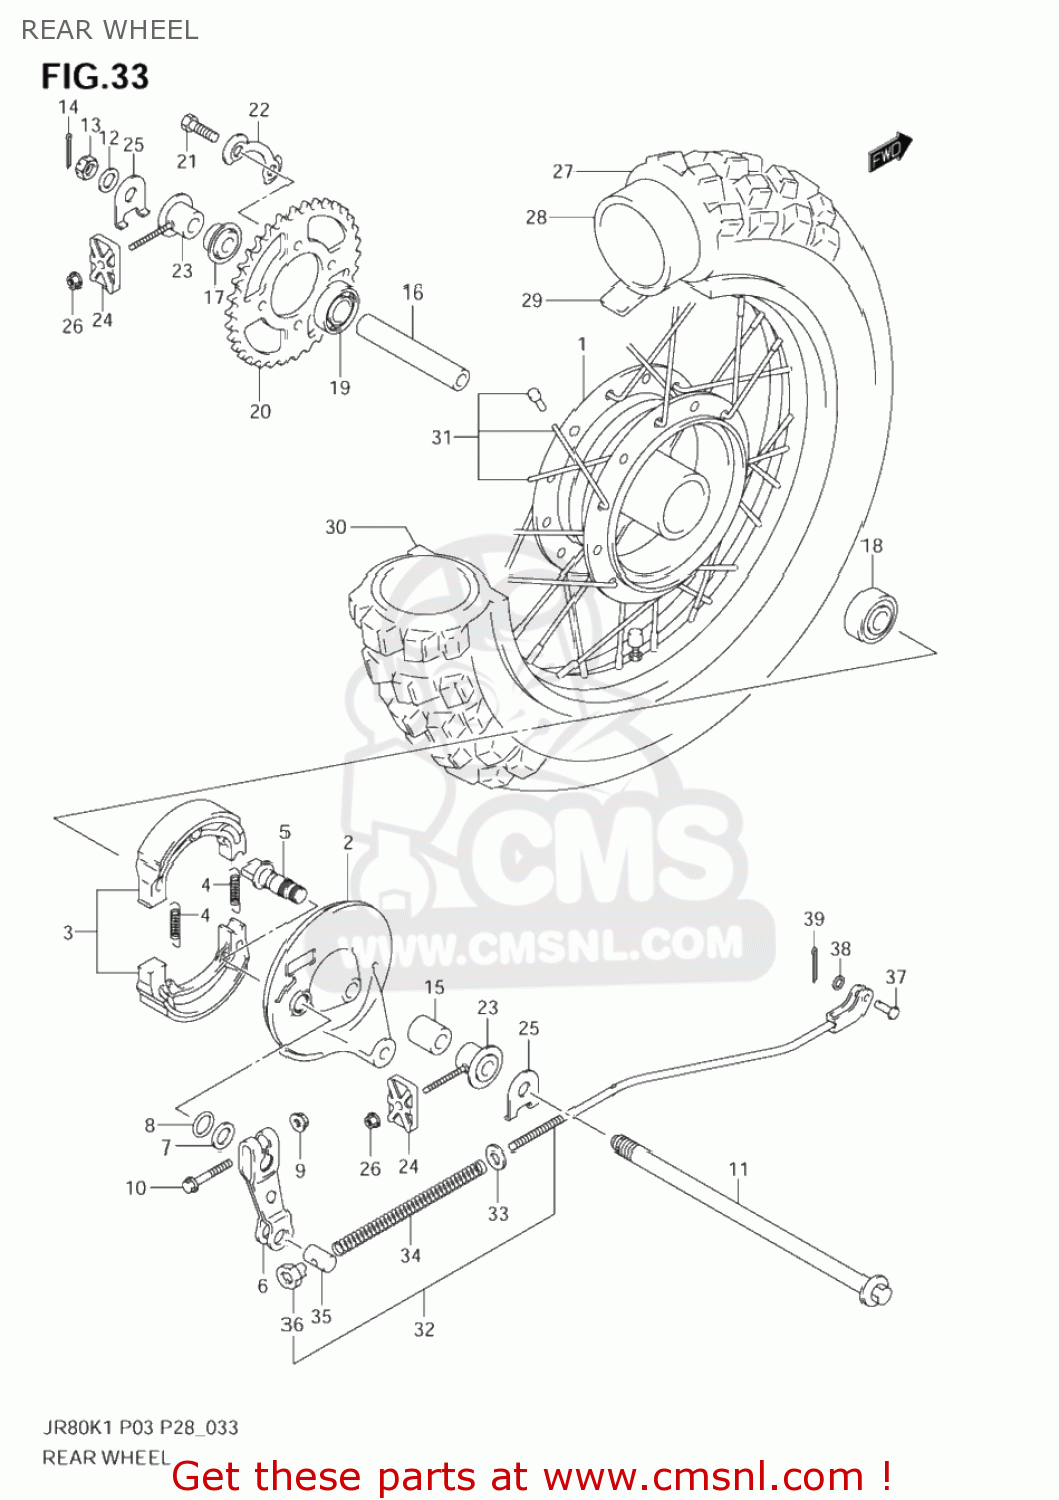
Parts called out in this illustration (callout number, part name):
1	HUB,RR
2	PANEL,RR BRAKE ANCHOR
3	SHOE SET,BRAKE (NAS)
4	SPRING(L:35.8)
5	CAM,BRAKE
6	LEVER,RR BRAKE CAM
7	WASHER(14.5X22X1.6)
8	O RING(D:2.5,ID:13.8)
9	NUT
10	BOLT
11	AXLE,RR
12	WASHER
13	NUT,M12X1.25X1
14	COTTER PIN
15	SPACER(12.1X22X22)
16	SPACER(12.6X19X91)
17	SPACER,RR AXLE,L
18	BEARING
19	BEARING
20	SPROCKET,RR(NT:34)
21	BOLT(8X25)
22	WASHER
23	ADJUSTER,CHAIN
24	PLATE,CHAIN ADJUSTER GUIDE
25	WASHER,CHAIN ADJUSTER
26	NUT
27	TIRE(3.00 12)
28	TUBE,INNER
29	PROTECTOR,INNER TUBE
30	RIM,RR WHEEL(1.60X12)
31	SPOKE ASSY,RR WHEEL
32	ROD ASSY,RR BRAKE
33	WASHER
34	SPRING
35	PIN(11X18)
36	NUT
37	PIN(L:13.5)
38	WASHER
39	PIN
